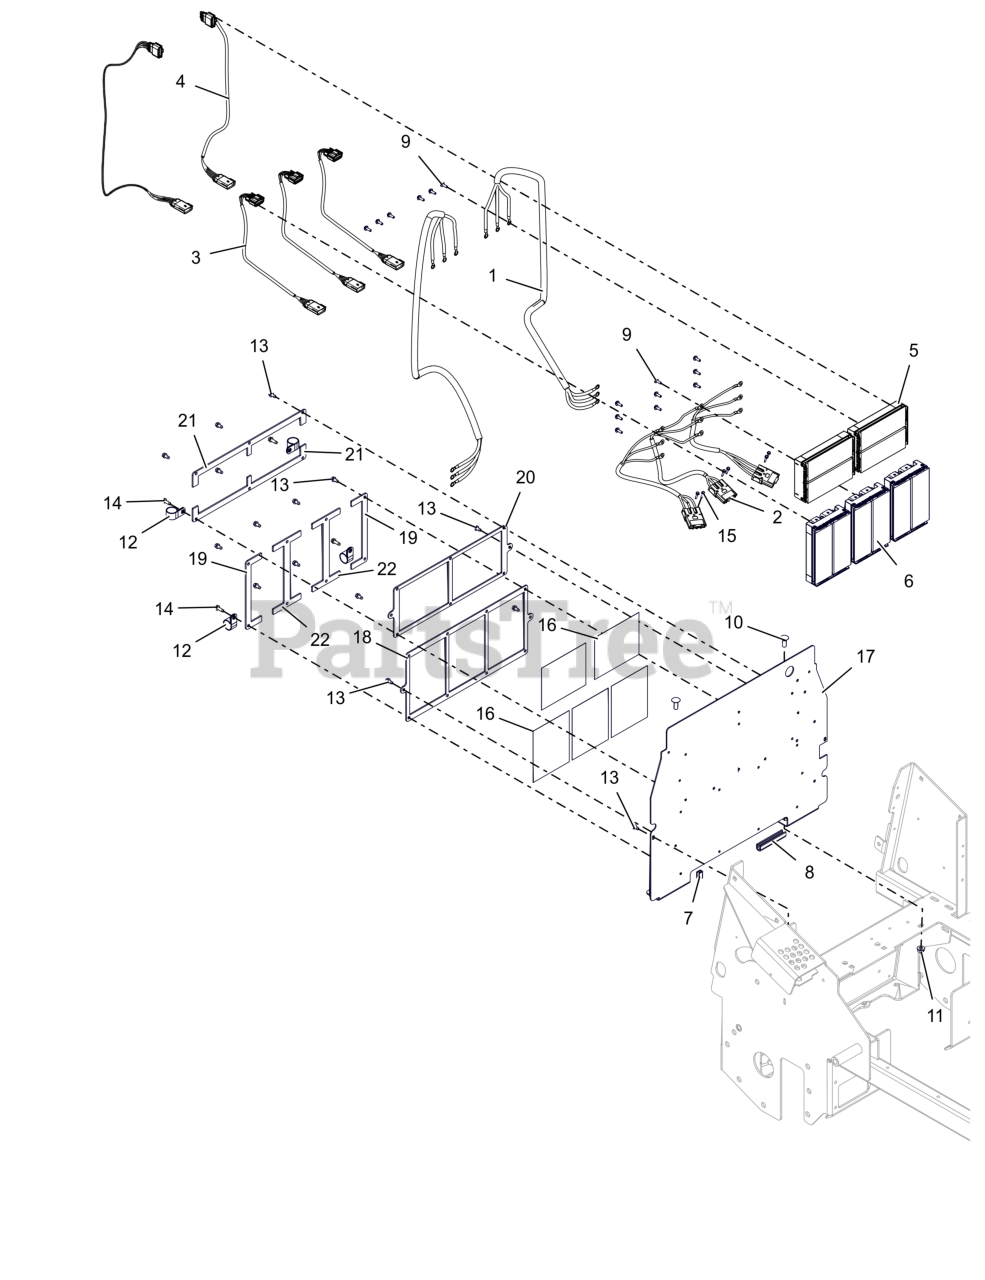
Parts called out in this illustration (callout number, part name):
1	HARNESS- TRACTION PHASE
2	HARNESS- DECK PHASE
3	HARNESS- DECK SIGNAL
4	HARNESS- TRACTION SIGNAL
5	KIT, PSEV DRIVE CONTROLLER
6	KIT, MY23 48 DECK CONTROLLER
7	STRIP, COWL
8	GUARD, PLASTIC EDGE AND TRIM
9	BLT,HEX M5-.8X16 EP30 G8.8 ZCC
10	BLT,RHSSN .38-16X1.00 G5 ZCC
11	NUT-LK-CTR-FLG .375-16 GF ZCC
12	CLAMP, COUSHIONED STEEL REV
13	SCR-TAP .25-20X.50 HWH ZCC
14	SCR,TAP .25-20X.75 HWH TR ZCC
15	SCR-TAP #6-32X.75 HWH ZCC
16	PAD, THERMAL
17	PANEL, CONTROLLER MTG
18	PLATE- HEAT SINK SPCR
19	PLATE- LOWER CONTROLLER MTG
20	PLATE- HEAT SINK SPCR
21	PLATE- UPPER CONTROLLER MTG
22	PLATE, LOWER CONTROLLER MTG (BLACK)
